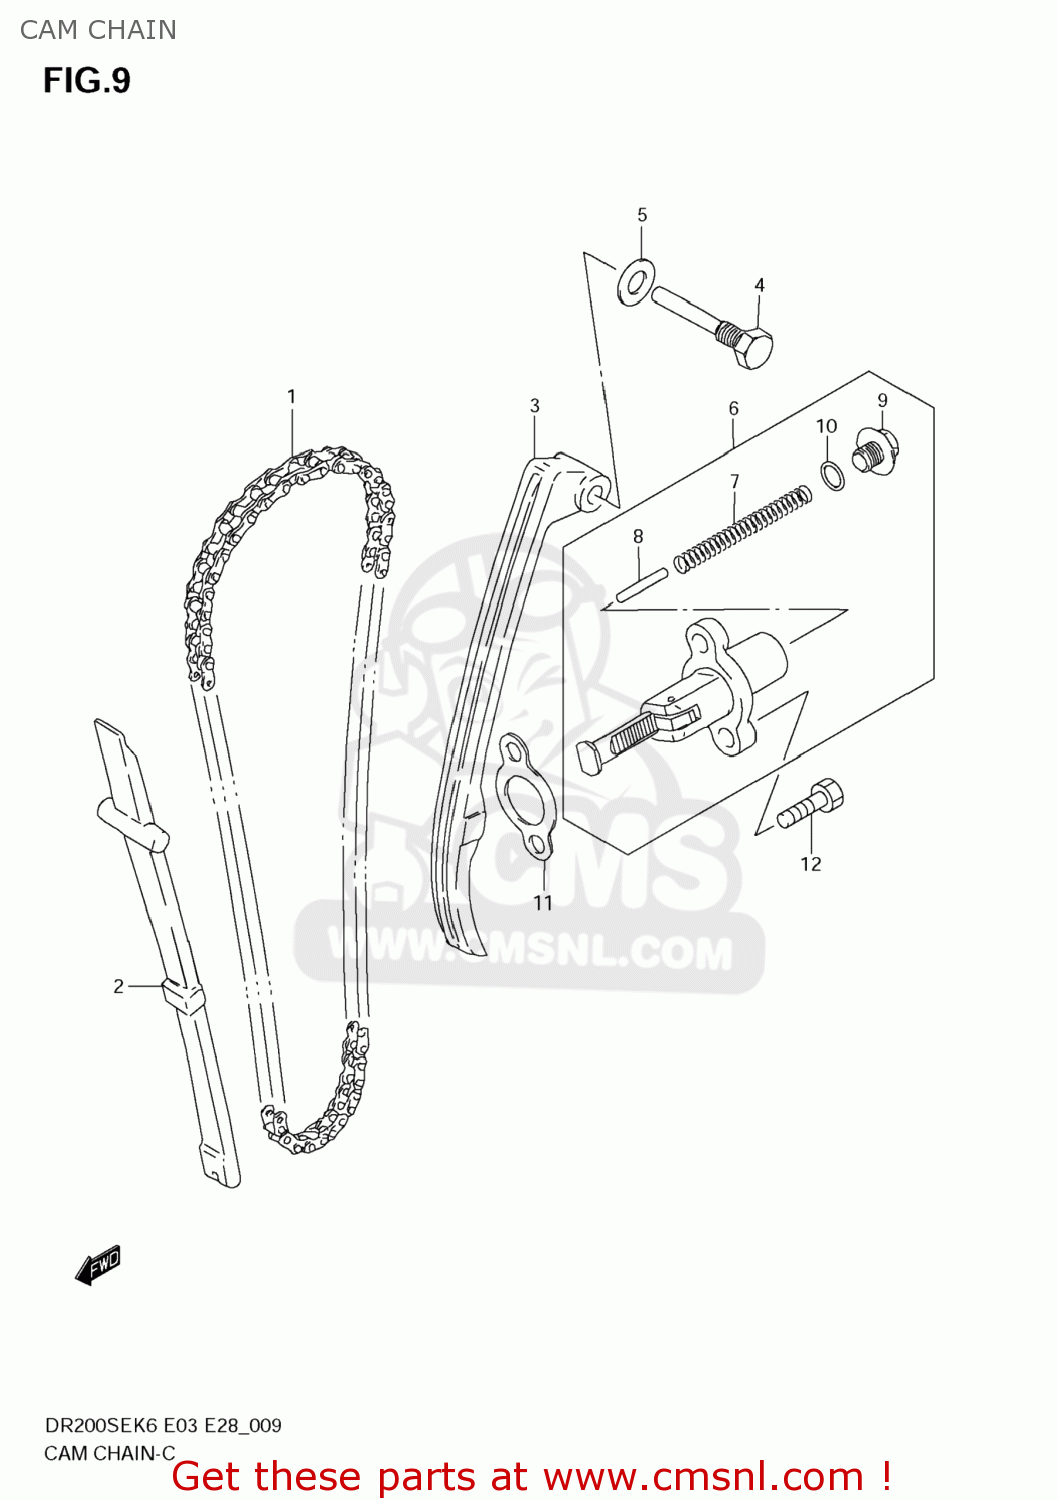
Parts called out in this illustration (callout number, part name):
1	CHAIN,CAMSHAFT DRIVE 102L
2	GUIDE,CAM CHAIN
3	TENSIONER,CAM CHAIN
4	BOLT,CAM CHAIN TENSIONER
5	GASKET(8.2X14X1) (NAS)
6	ADJUSTER ASSY,TENSIONER
7	SPRING
8	BAR
9	PLUG
10	O RING
11	GASKET,TENSIONER ADJUSTER (NAS)
12	BOLT
